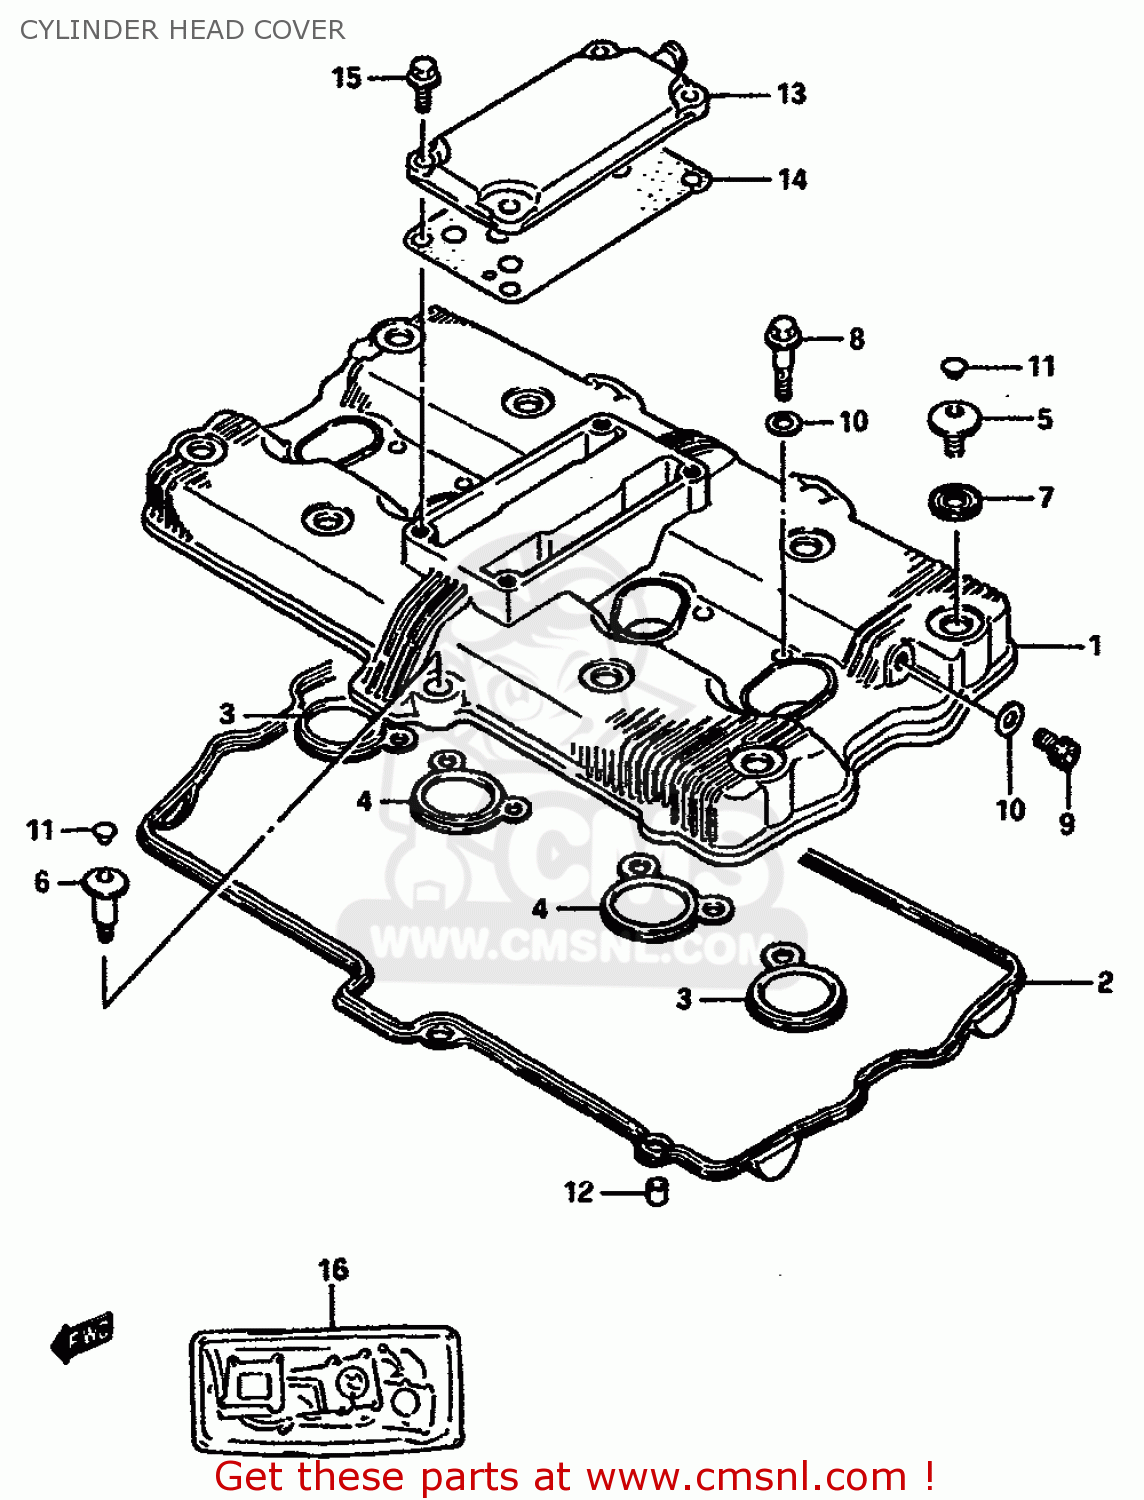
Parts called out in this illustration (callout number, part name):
1	COVER,CYLINDER HEAD
2	GASKET,CYLINDER HEAD COVER (NAS)
3	GASKET (NAS)
4	GASKET,HEAD COVER NO.3 (NAS)
5	BOLT(7X17.5)
6	BOLT(7X31)
7	WASHER
8	BOLT,UNION 8X35
9	PLUG, HEAD COVER
10	GASKET 8.2X14X1 (NAS)
11	CAP(OD:10)
12	PIN
13	COVER,BREATHER
14	GASKET (NAS)
15	BOLT
16	GASKET SET (MCA)
